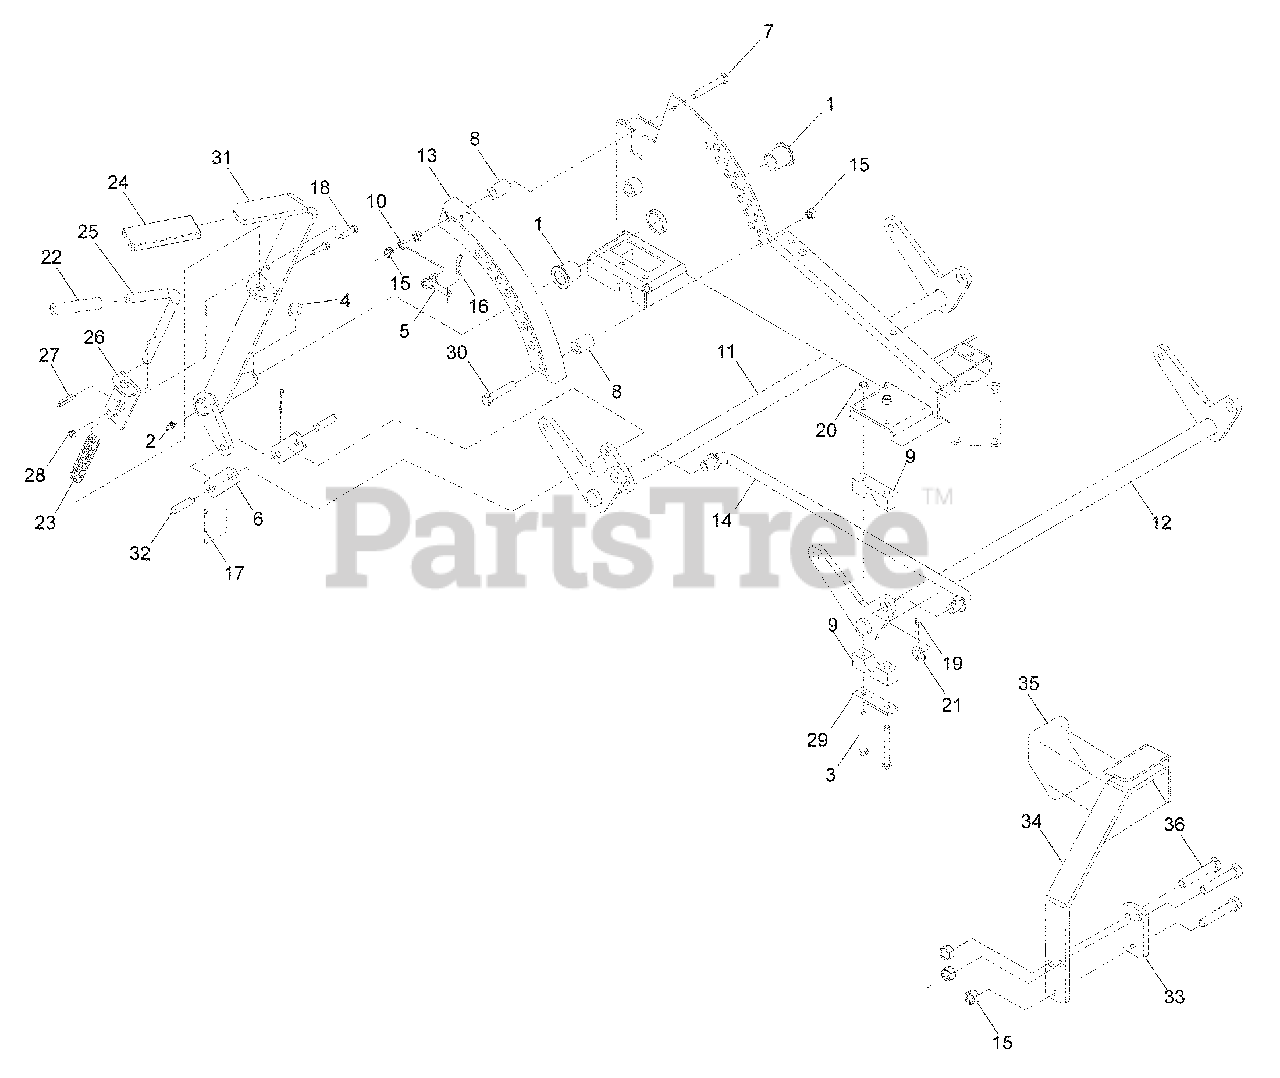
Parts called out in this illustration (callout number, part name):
3	HCS 5/16-18 x 2¾
4	E-RING 7/8
5	PIN LIFT ½ x 2 w/RINGS
7	HCS 3/8-16 x 2¾
9	BLOCK, PILLOW
11	SHAFT, REAR LIFT
12	SHAFT, FRONT LIFT
13	PLATE, ADJUSTMENT
14	CROSS LINK
15	NUT 3/8-16 HEX NYLOC
16	PIN, HAIR .120 x 2½
17	PIN, COTTER 1/8 x ¾
18	HCS ¼-20 x ¾
19	PIN, COTTER, 5/32 x 1¼
20	NUT 5/16-18 HEX NYLOC
22	GRIP, VINYL
23	SPRING, COMPRESSION
24	GRIP, LIFT LEVER
25	L PIN, ½ x 6.69
27	PIN, GROOVED 3/16 x 1¼
28	NUT ¼-20 CENTERLOCK
29	REINFORCED BAR
30	HCS 3/8-16 x 2½
31	LIFT LEVER
32	PIN, CLEVIS 3/ x 11/
33	TIGHTING PLATE
34	LIFT PEDAL
35	ANTI-SKID PAD
36	HCS 3/8-16 x 1½
